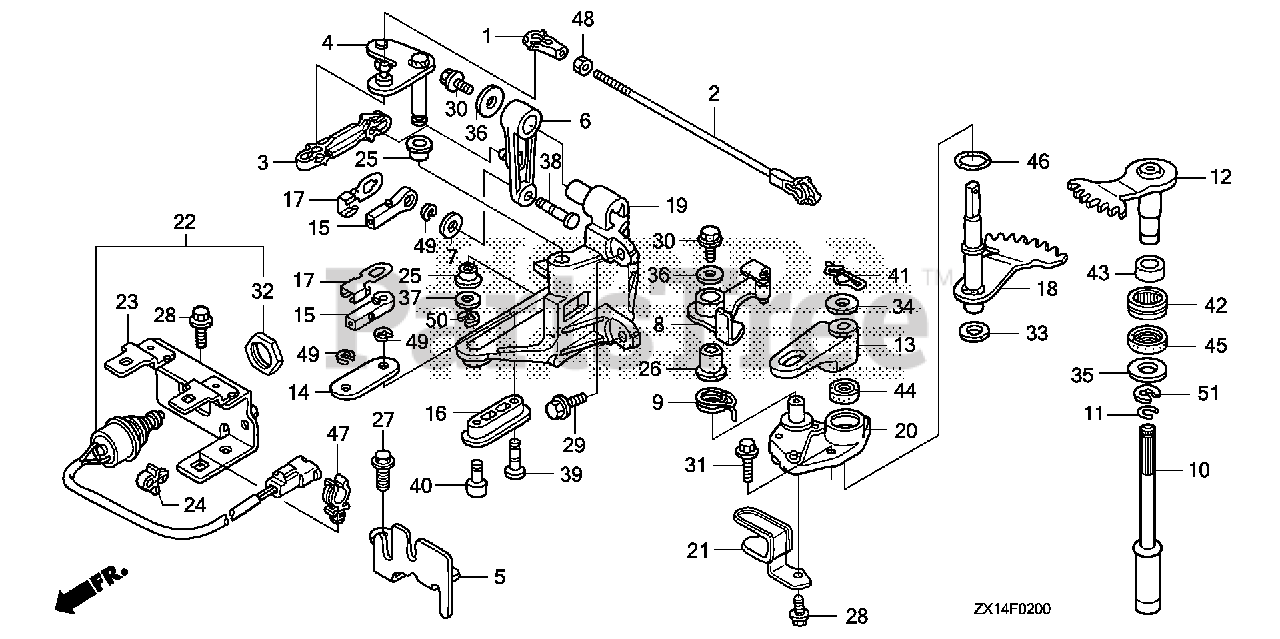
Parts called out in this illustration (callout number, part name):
1	LINKAGE, PIVOT
2	ROD, THROTTLE
3	LINK, THROTTLE
4	PLATE, THROTTLE
5	PLATE, REMOTE CONTROL CABLE
6	ARM, THROTTLE
7	WASHER, PIVOT
8	ARM, CLICK
9	SPRING, CLICK
10	ROD A, SHIFT (L)
11	RING, STOPPER
12	SHAFT A, SHIFT
13	ARM, SHIFT
14	PLATE, SHIFT PIVOT
15	PIVOT, SHIFT
16	PIVOT, SHIFT SLIDE
17	PLATE, LOCK
18	SHAFT B, SHIFT
19	BRACKET, SHIFT LINK
20	HOLDER, SEAL *NH8* (DARK GRAY)
21	BRACKET A, CABLE
22	SWITCH ASSY., NEUTRAL
23	BRACKET, NEUTRAL SWITCH
24	CLIP, BRAKE PIPE (A) (FOR NEUTRAL SWITCH)
25	BUSH A, COVER LOCK
26	BUSH, BLADE BRAKE
27	BOLT, FLANGE (6X16)
28	BOLT, FLANGE (6X14)
29	BOLT, FLANGE (6X18)
30	BOLT, FLANGE (6X12) Use from Frame SN 1005249.
31	BOLT, FLANGE (6X20) (ENGINE NO.)
32	NUT, HEX. (20MM) Use up to Frame SN 1300359.
33	WASHER, SHIFT SHAFT
34	WASHER, PLAIN (12MM)
36	WASHER, PLAIN (6MM)
37	WASHER, PLAIN (8MM) Use from Frame SN 4800713.
39	PIN, SHIFT LINK
41	PIN, SNAP (12MM)
42	BEARING, NEEDLE (20X28X13) (SOLID)
43	RING (INNER) (15X20X13)
44	OIL SEAL (14X26X6)
45	SEAL, WATER (14X26X8)
46	O-RING (25X2.4) (NOK)
47	HOLDER, DRAIN TUBE
48	NUT, HEX. (5MM)
49	E-RING (4MM)
50	E-RING (6MM)
51	E-RING (12MM)
